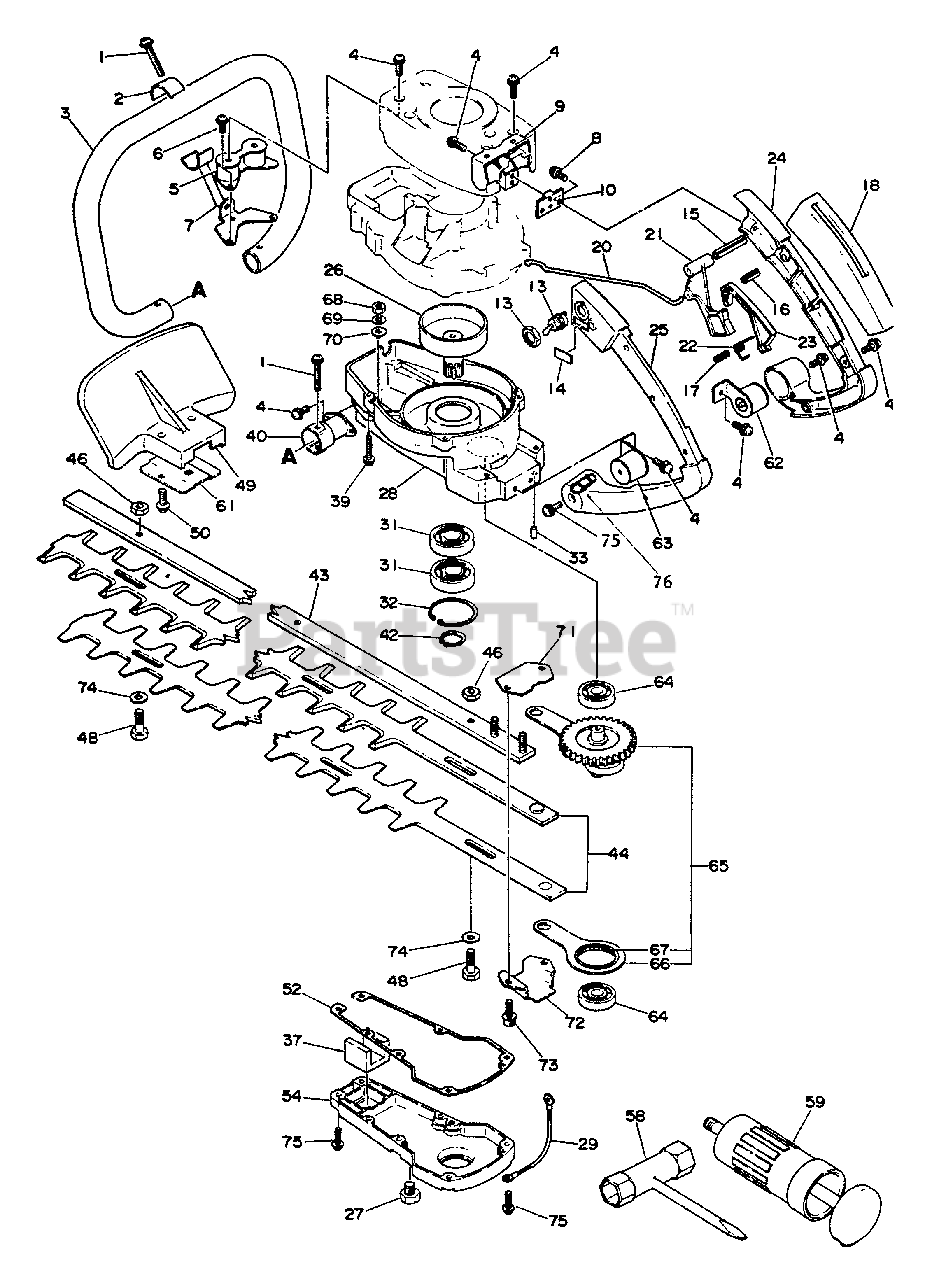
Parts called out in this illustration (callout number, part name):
1	SCREW - 4X30
3	HANDLE - FRONT
4	SCREW - 4X12
6	SCREW - 4X8
7	BRACKET, HANDLE
8	SCREW - 4X10
10	PLATE
13	IGNITION SWITCH KIT
14	LABEL - STOP
15	PIN - SPRING -- 5X32
16	PIN - SPRING -- 4X16
17	PIN - SPRING -- 3X14
20	ROD, THROTTLE
21	TRIGGER, THROTTLE
23	LOCKOUT, THROTTLE
24	HANDLE - REAR
25	HANDLE - REAR
26	DRUM, CLUTCH
27	BOLT - 8X8
28	CASE, GEAR
29	LEAD - GROUND
31	BEARING, BALL - 6003
32	RING, RETAINING - 35
33	PIN - LOCATING
37	SEAL, FELT
39	SCREW - 4X22
40	CUSHION
42	RING, RETAINING - 16
43	SUPPORT, BLADE
44	TRIMMER BLADE SET
46	LOCKNUT - 6
49	GUARD
50	SCREW - 5X12
52	GASKET, GEAR CASE
54	LID, GEAR CASE
58	T-WRENCH
59	PUMP, GREASE
62	CUSHION
63	CUSHION
64	BEARING, BALL - 6200
65	GEAR ASSY
66	CONNECTING ROD ASSY
67	BEARING, NEEDLE
69	LOCKWASHER - 6
70	WASHER - 6
71	PLATE, GUIDE
72	GUIDE
73	SCREW - 5X14
75	SCREW - 4X14
76	SPACER
